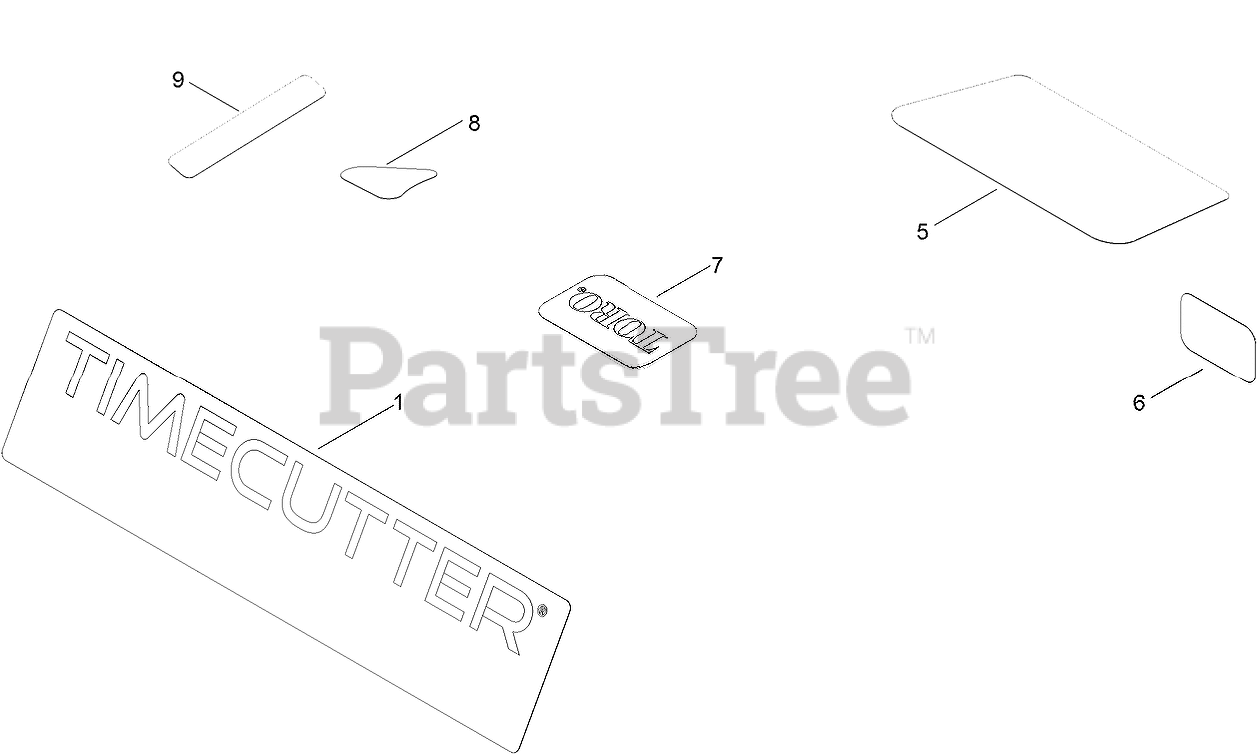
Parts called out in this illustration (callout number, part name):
1	DECAL-TIMECUTTER
5	DECAL-ENGINE
6	PLACARD-INTAKE
8	DECAL-DRAIN, OIL
9	DECAL-SHUTDOWN
